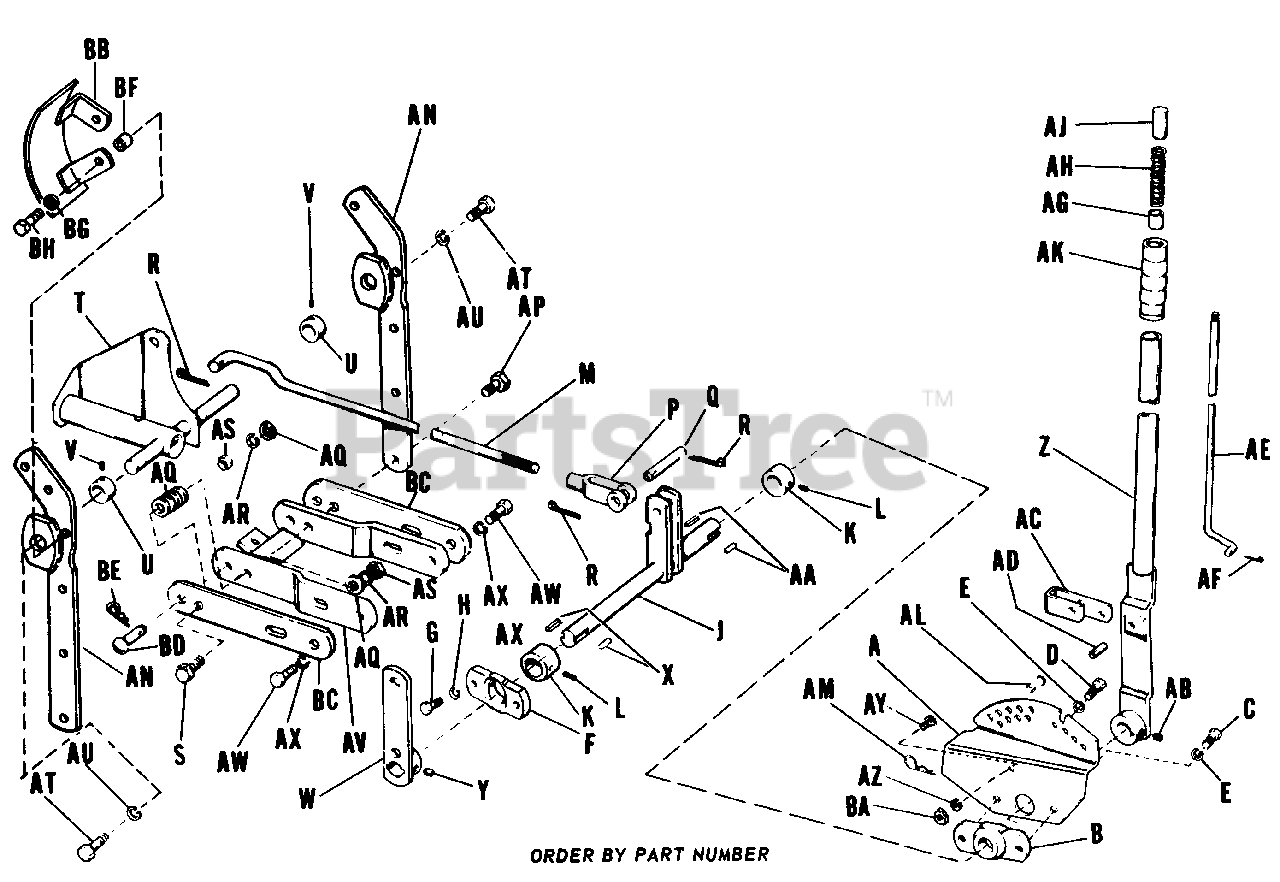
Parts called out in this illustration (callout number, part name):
A	Lift Lever Quadrant
B	Lift Lever Bearing
C	Hex. Cap Screw, 3/8"-16 x 7/8"
D	Hex. Cap Screw, 3/8"-16 x 1-1/4"
E	Lock Washer, 3/8"
F	Lift Lever Bearing
G	Hex. Cap Screw, 3/8"-16 x 7/8"
H	Lock Washer, 3/8"
J	Lift Shaft Assembly
K	Set Collar
L	Set Screw 5/16"-18 x 5/16"
M	Rear Lift Rod
P	Adj. Yoke End
R	Cotter Pin, 1/8" x 1"
S	Hex. Cap Screw, 7/16"-14 x 1-3/4"
T	Tiller Lift Assembly
U	Set Collar
V	Set Screw, 5/16"-18 x 5/16"
W	Front Lift Lever Assembly
Y	Set Screw, 5/16"-18 x 1/4"
Z	Lift Lever Assembly
AB	Set Screw, 5/16"-18 x 1/4"
AC	Lift Lever Latch
AE	Latch Rod
AF	Cotter Pin, 3/32" x 3/4"
AJ	Thumb Button
AK	Handle Grip
AM	Spring Clip
AN	Arm Assembly
AP	Hex. Capscrew, 7/16"-14 x 1-1/2"
AQ	Plain Washer, 3/8"
AR	Lock Washer, 3/8"
AS	Full Hex. Nut, 7/16"
AT	Hex. Cap Screw, 7/16"-14 x 1"
AU	Lock Washer, 7/16"
AV	Draw Bar Assembly
AW	Hex. Cap Screw, 7/16"-14 x 1-1/4"
AX	Lock Washer, 7/16"
AY	Hex Capscrew, 1/4-20 x 5/8" lg.
AZ	Lock Washes, 1/4"
BA	Hex Nut 1/4-20
BB	Pulley Guard Assembly
BD	Round Head Pin
BE	Spring Clip
BG	Lock Washer, 7/16"
BH	Hex Capscrew, 7/16"-14 x 1-1/2"
